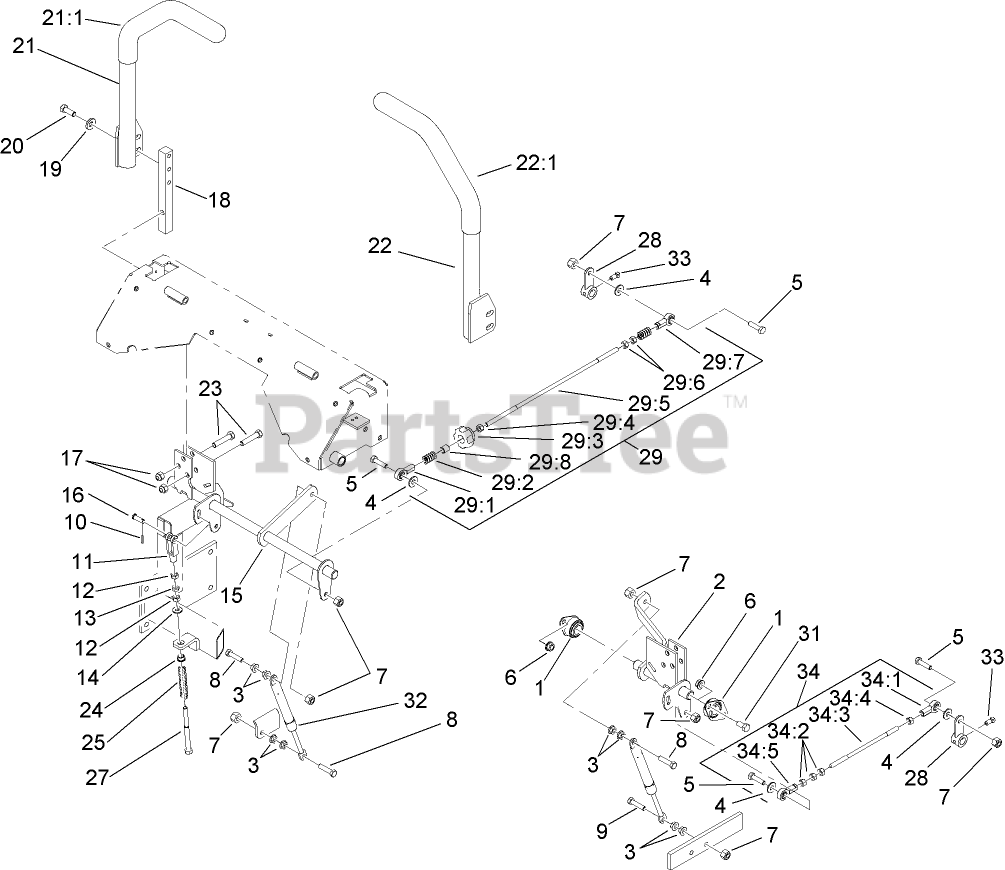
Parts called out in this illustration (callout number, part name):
1	BEARING-FLANGE, SIDE
2	CONTROL-MOTION, LH
3	NUT-HF
4	WASHER-FLAT
5	SCREW-HH
6	NUT-HHF, WHIZ
7	NUT-LOCK, NI
8	SCREW-HH
9	SCREW-HH
10	PIN-COTTER
11	YOKE-ADJUSTABLE
12	NUT-HEX
13	NUT-JAM
14	WASHER-FLAT
15	CONTROL-MOTION, RH
16	PIN-CLEVIS
17	NUT-LOCK, NI
18	ARM-SHAFT, CONTROL
19	WASHER-BELLEVILLE
20	SCREW-HH
21	RH LEVER ASM
21:1	Grip-Control, Motion
22	LH LEVER ASM
22:1	Grip-Control, Motion
23	SCREW-HH
24	BUSHING-FLANGED
25	SPRING-RETURN, NEUTRAL
27	BOLT-RETURN, NEUTRAL
28	ARM-CONTROL, HYDRAULIC
29	RH CONTROL ROD ASM
29:1	BALLJOINT-RH
29:2	SPRING-COMPRESSION
29:3	KNOB-TRACKING
29:4	NUT-HEX
29:5	ROD-CONTROL, RH
29:7	BALLJOINT-LH
29:8	SPACER-TUBE, PUMP LINK
31	SCREW-HH
32	DAMPER-CONTROL, MOTION
33	SCREW-SET
34	LH CONTROL ROD ASM
34:1	BALLJOINT-RH
34:2	NUT-HEX
34:3	ROD-CONTROL, LH
34:5	BALLJOINT-LH
